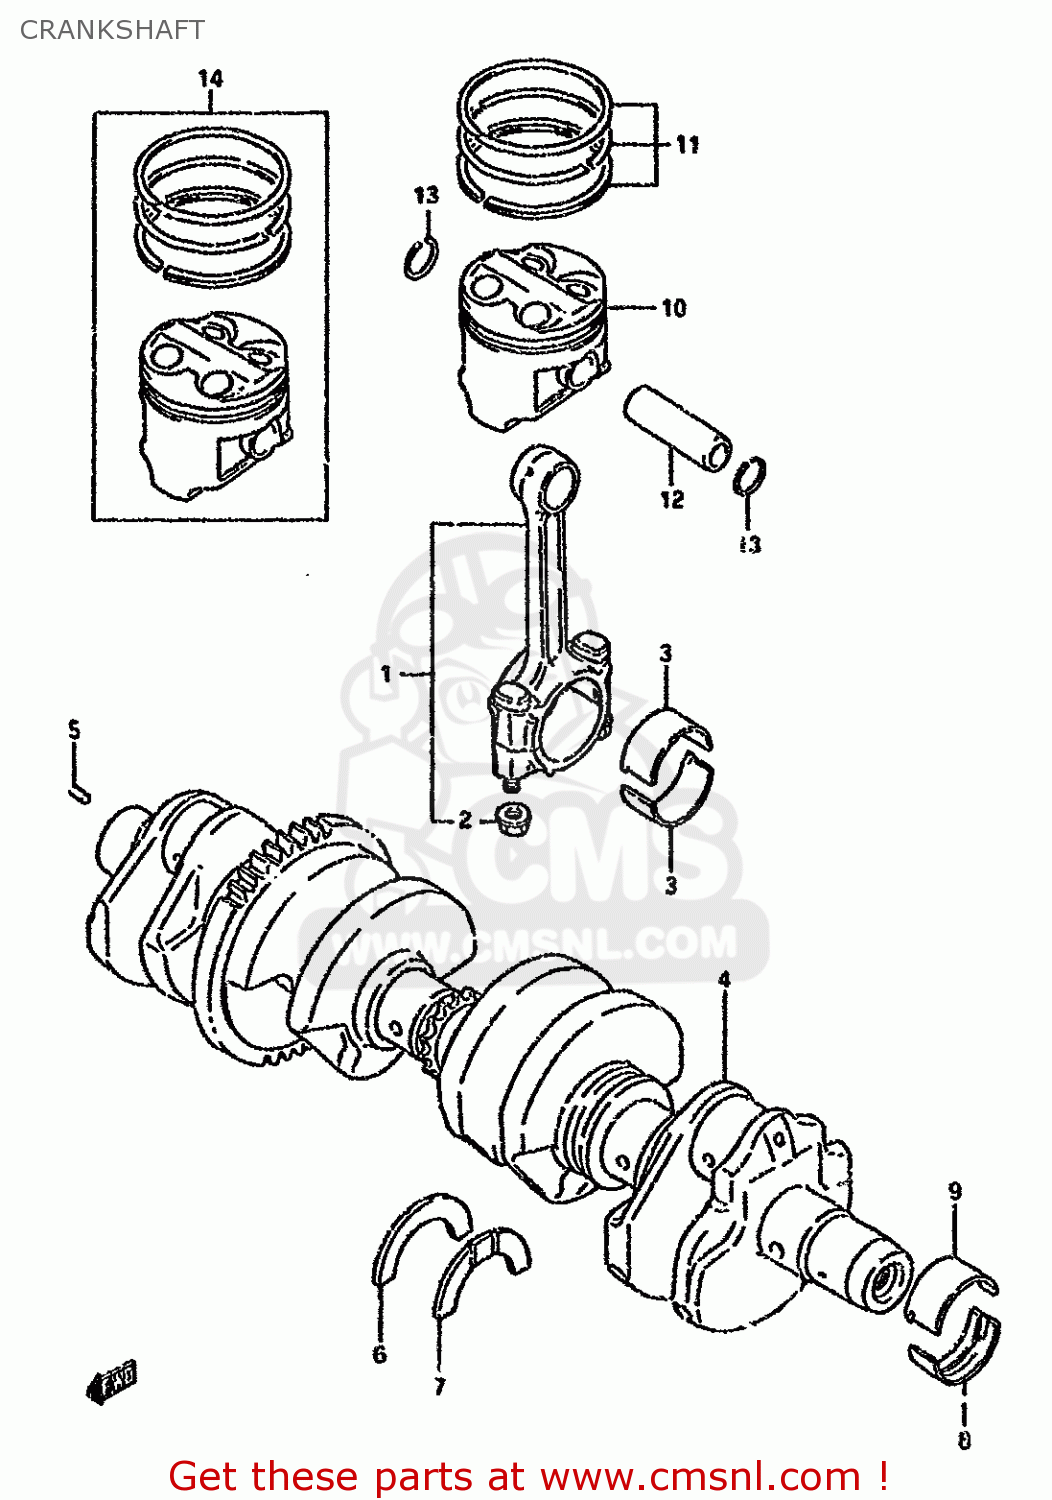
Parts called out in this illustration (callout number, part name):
1	ROD ASSEMBLY,CONNECTING
2	NUT
3	BEARING,CRANK PIN
4	CRANKSHAFT SET
5	PIN
6	PLATE,CRANK THRUST
7	PLATE,CRANK THRUST
8	BEARING,CRANKSHAFT LWR
9	BEARING,CRANKSHAFT UPR
10	PISTON
11	RING SET,PISTON
12	PIN,PISTON
13	CIRCLIP
14	PISTON SET (OS:1.0)
